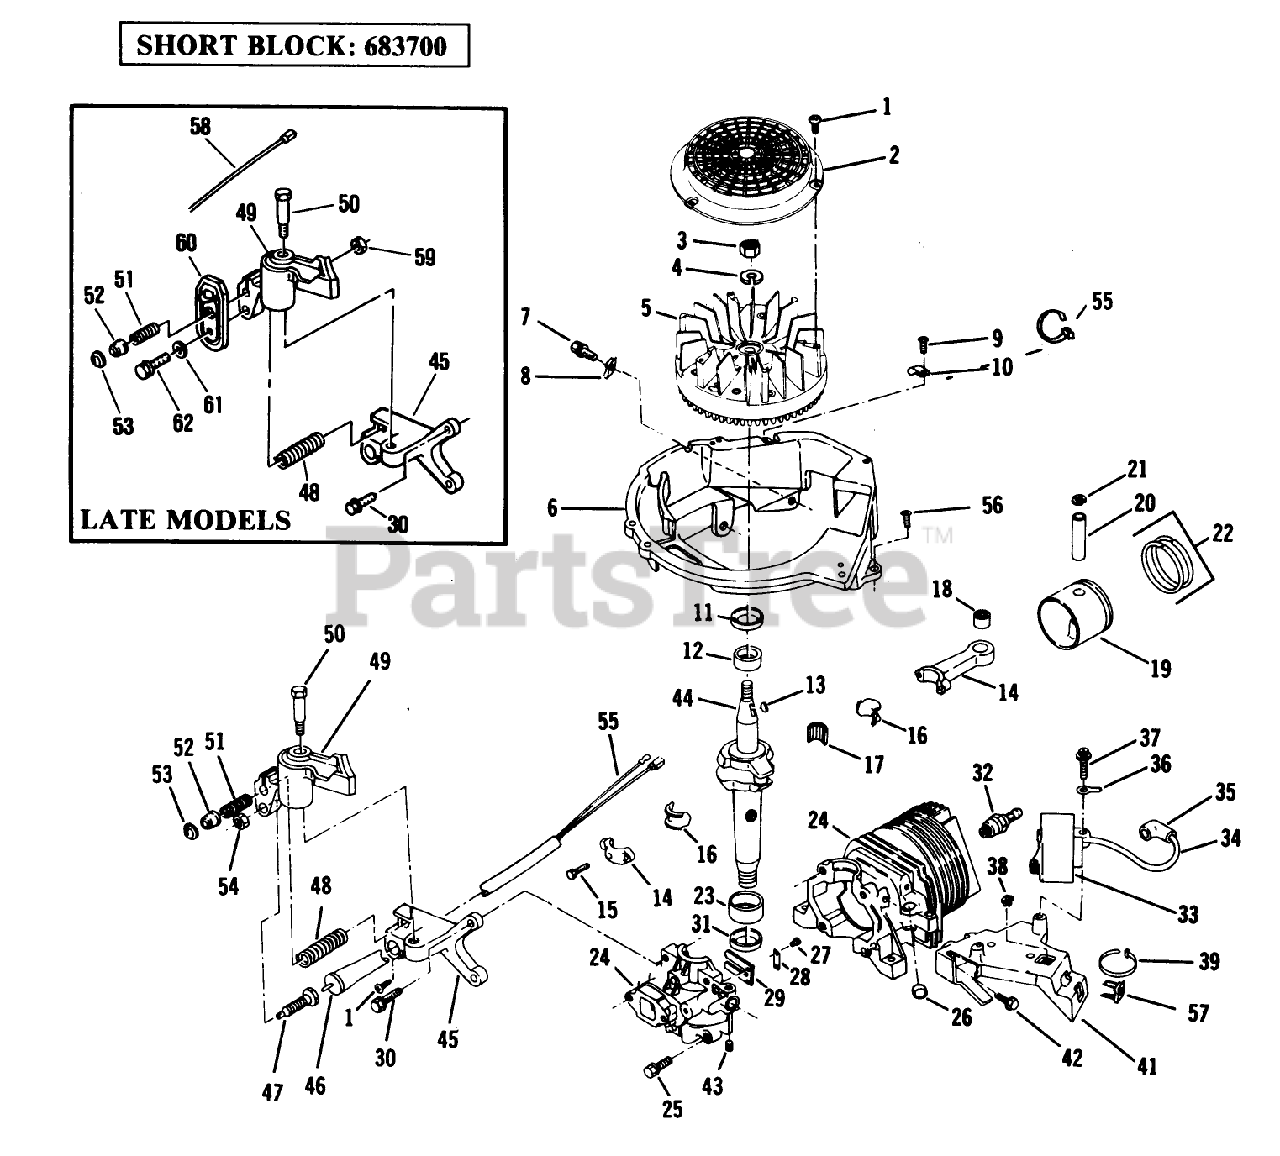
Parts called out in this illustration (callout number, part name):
1	SCREW F
2	SCREEN F'WHEEL S
3	NUT
5	FLYWHEEL ASSY F
7	SCREW-SEMS
9	SCREW F
12	BEARING V
13	KEY
15	SCREW-HSH
16	LINER ASM
18	BEARING AY F
21	RING-RETAINING
23	BEARING V
25	SCREW S
26	PLUG-CORE VF
28	PLATE-BACKUP, REED
31	SEAL-OIL
34	HT LEAD&COVER XEV
36	TERMINAL S
38	NUT-CLIP
45	BRACKET-BRAKE F
47	PLUNGER S
48	SPRING-BRAKE
51	SPRING
52	ACTUATOR-LEVER, BRAKE
53	RETAINER S
56	SCREW F
57	NUT-CLIP
58	WIRE LEAD AY F
59	NUT C/LOCK E
61	WASHER
